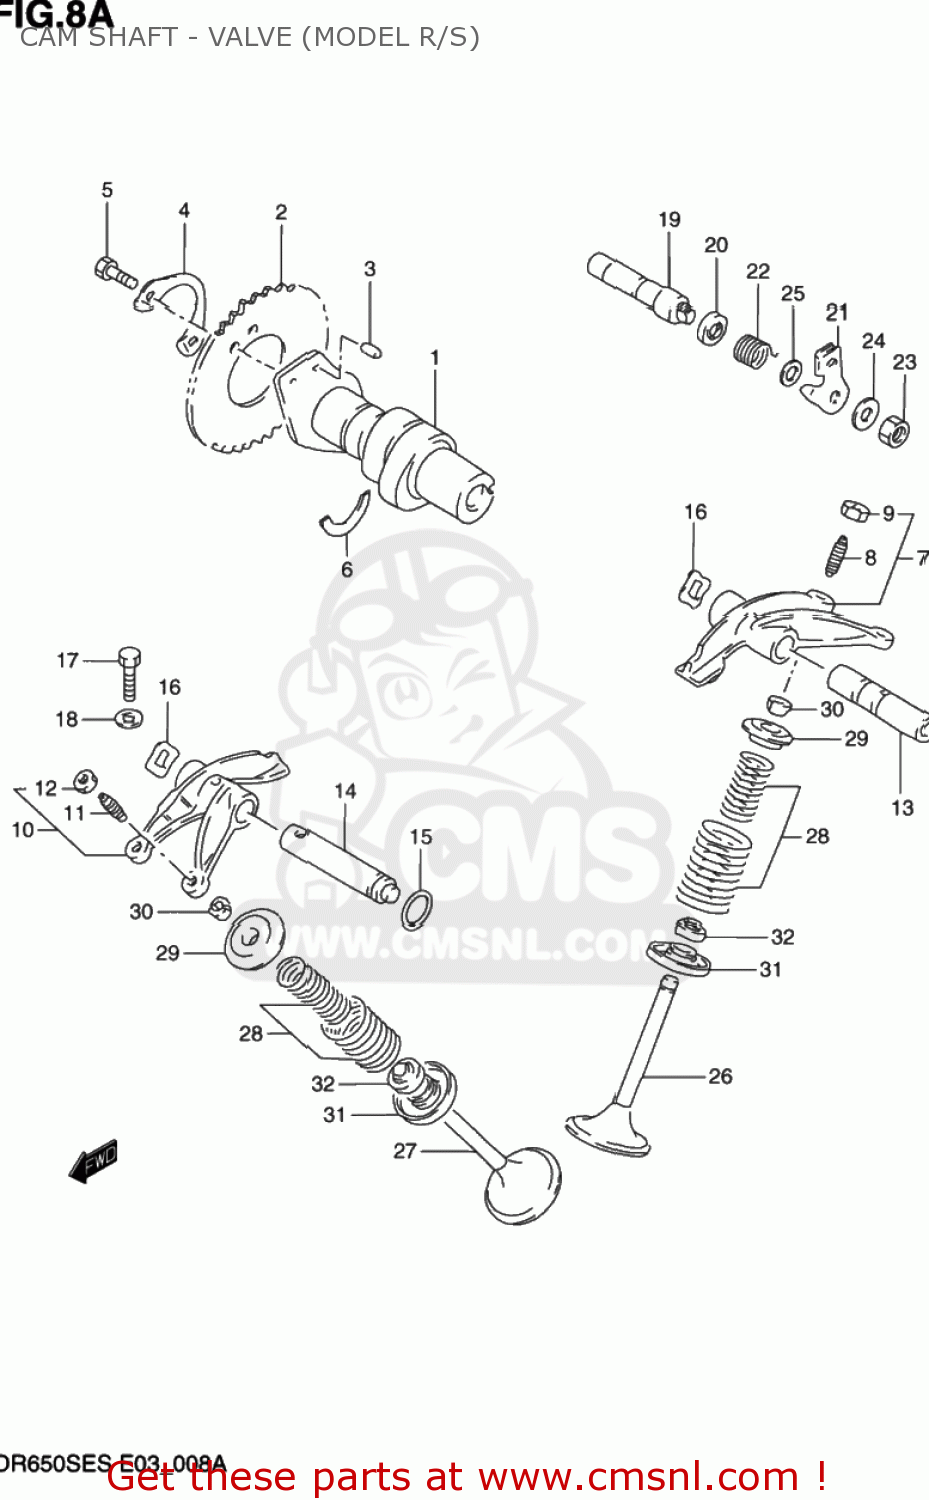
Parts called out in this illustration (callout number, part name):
1	CAMSHAFT
2	SPROCKET,CAMSHAFT(NT:42)
3	PIN
4	WASHER,CAM CHAIN SPROCKET
5	BOLT(6X12.5)
6	C RING
7	ARM,VALVE ROCKER INTAKE
8	SCREW,TAPPET ADJUSTING
9	NUT,ADJUSTING SCREW
10	ARM,VALVE ROCKER EXHAUST
11	SCREW,TAPPET ADJUSTING
12	NUT,ADJUSTING SCREW
13	SHAFT,VALVE ROCKER ARM INTAKE
14	SHAFT,EXHAUST VALVE ROCKER ARM
15	O RING(D:1.9,ID:8.6)
16	WASHER
17	BOLT
18	GASKET(5.8X13X1.2) (NAS)
19	SHAFT,DECOMP
20	SEAL,OIL(10X17X6)
21	LEVER,DECOMPRESSION SHAFT
22	SPRING
23	NUT
24	WASHER
25	WASHER(8.5X13X1.6)
26	VALVE,INTAKE
27	VALVE,EXHAUST
28	SPRING SET,VALVE
29	RETAINER,VALVE SPRING
30	COTTER VALVE
31	SEAT,VALVE SPRING
32	SEAL,OIL(7X14.4X9)
